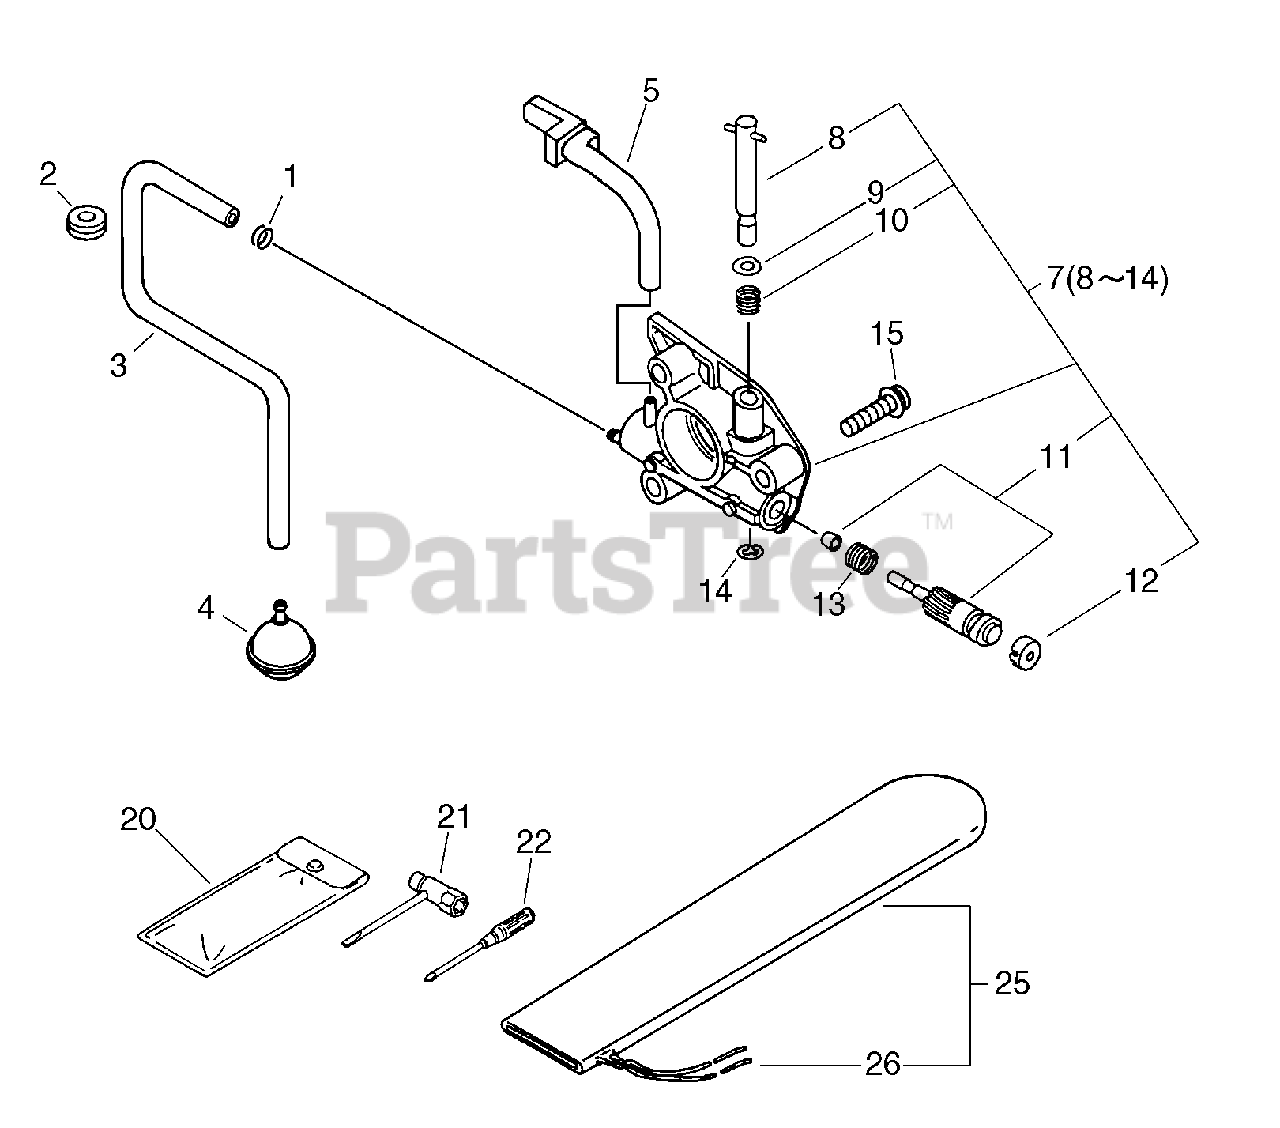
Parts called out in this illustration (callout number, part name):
1	CLIP Ø6.5 MM
3	PIPE, OIL
4	FILTER, OIL
5	PIPE, OIL OUTLET
7	AUTO-OILER ASSY
8	SCREW, ADJUSTER
11	PLUNGER ASSY
12	CAP, OIL PUMP
15	SCREW 4×16
20	BAG, TOOL
21	T-WRENCH 10×19 MM
22	SCREWDRIVER, PHILLIPS
25	COVER, GUIDE BAR
26	ROPE 5×900
